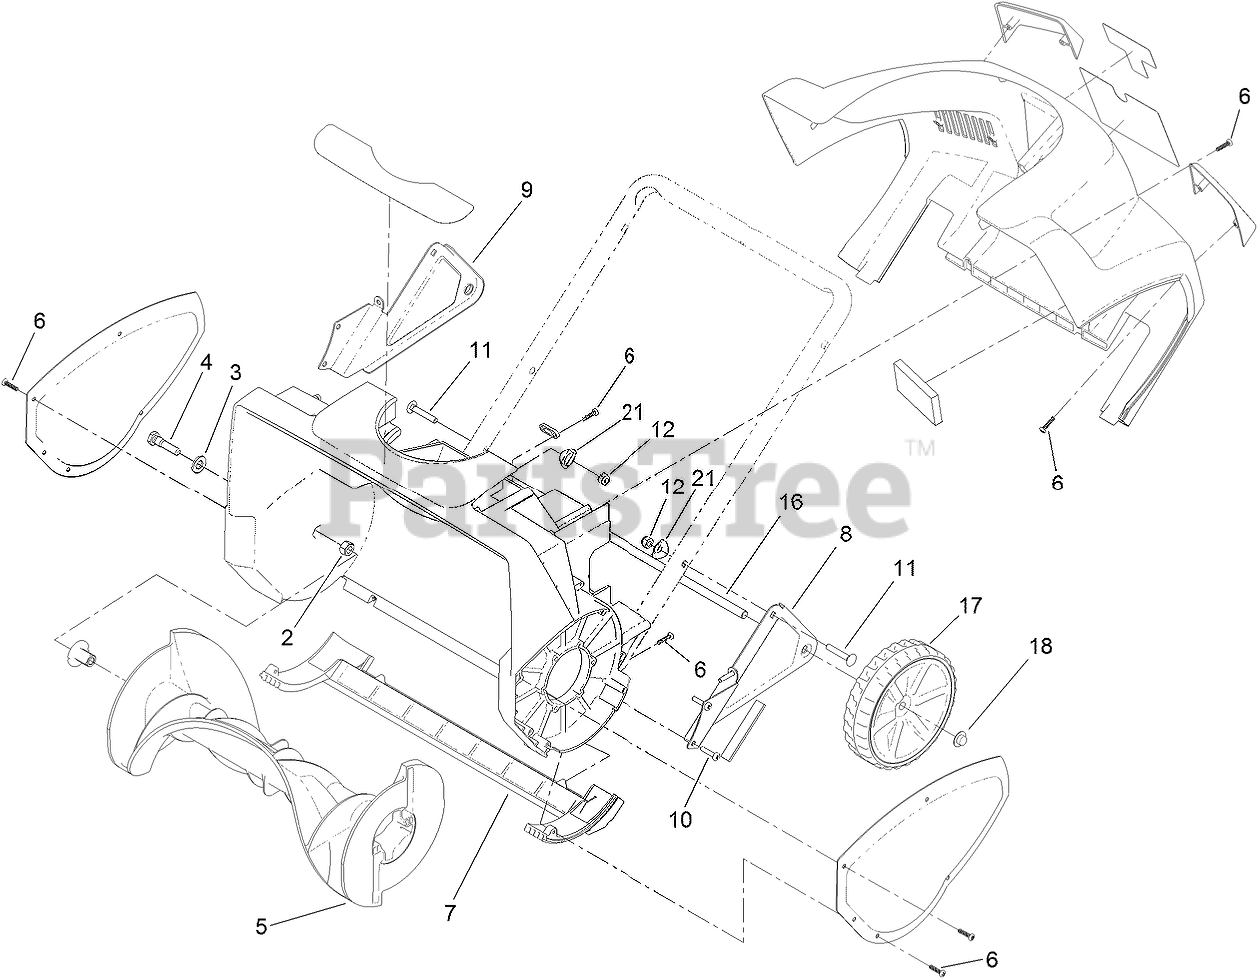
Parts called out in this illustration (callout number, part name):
2	NUT-HEX
3	WASHER-FLAT
4	PIN-ROTOR
5	ROTOR ASM
6	SCREW-PPH
7	SCRAPER
8	BRACKET-WHEEL, LH
9	BRACKET-WHEEL, RH
10	SCREW-PPH
11	BOLT-CARR
12	NUT-HEX
16	AXLE-WHEEL
17	WHEEL ASM
18	NUT-PUSH
21	WASHER-CUP
